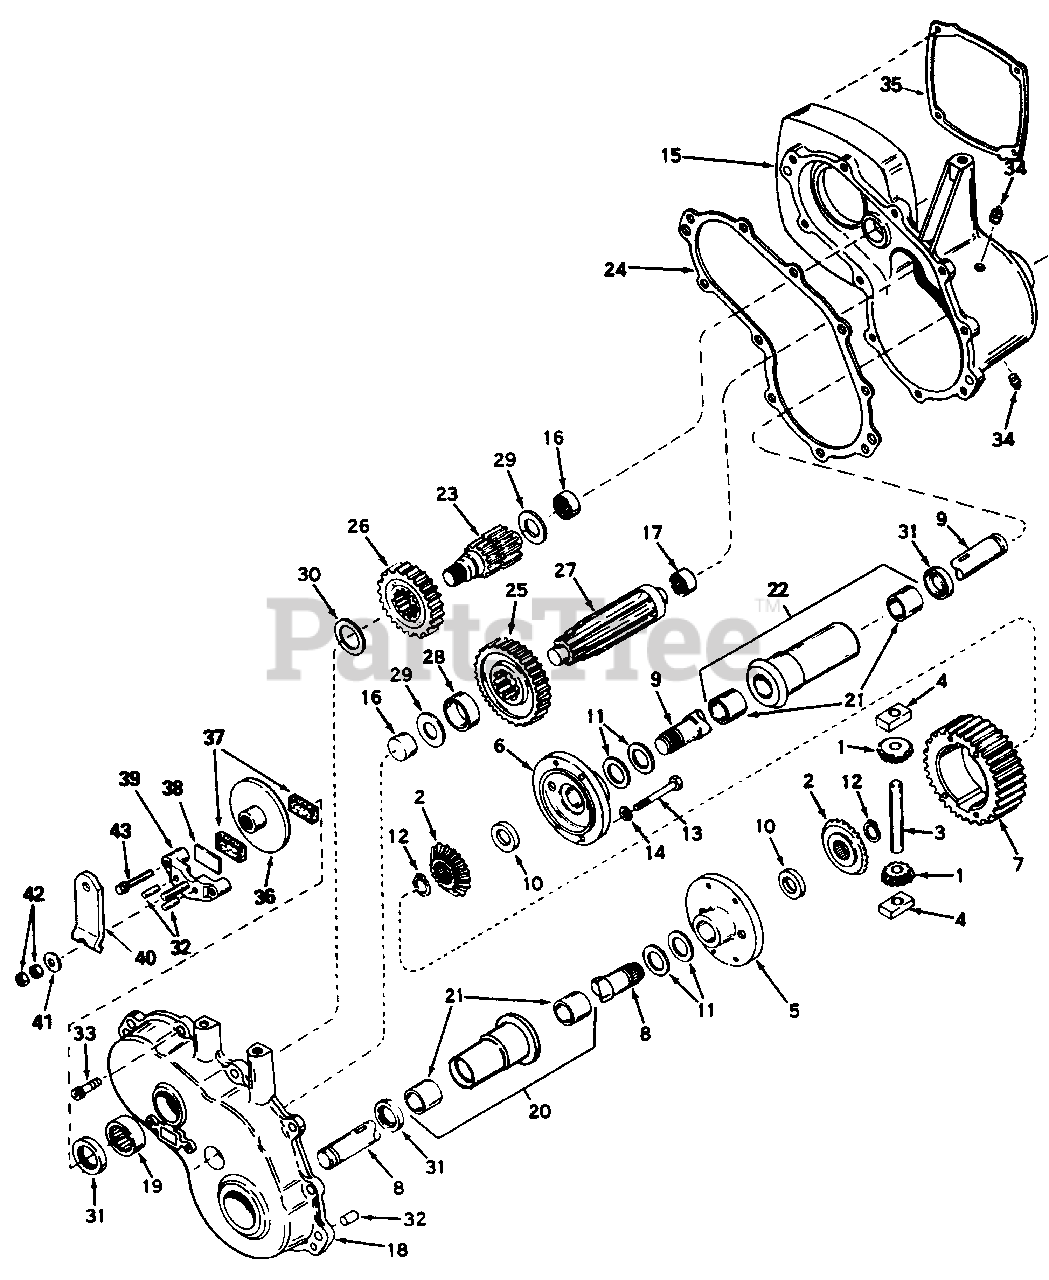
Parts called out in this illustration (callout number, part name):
1	PINION, Bevel
2	GEAR, Bevel
3	PIN, Drive
4	BLOCK, Drive
5	CARRIER, Differential
6	CARRIER, Differential
7	GEAR, Ring
8	AXLE (13-7/32" long)
9	AXLE (15-3/16" long)
11	WASHER, Thrust
12	RING, Snap
13	SCREW, Hex Hd.. 1/4-20 x 2-1/4
14	LOCKWASHER, 1/4
15	CASE ASSY. (Includes Ref. Nos. 16 & 17)
16	BEARING, Needle
17	BEARING, Needle
18	COVER ASSY. (Includes Ref. Nos. 16 & 19)
19	BEARING, Needle
20	HOUSING & BUSHING ASSY. (6-5/8" long)
22	HOUSING & BUSHING ASSY. (8-5/8" long)
23	SHAFT, Brake
24	GASKET, Case-to-Cover
25	GEAR, Output
26	Gear, Idler
27	SHAFT, Output
31	SEAL, Oil
32	PIN, Dowel
33	SCREW, Hex Wash. Hd., Thd. Form., 1/4-20 x
34	PLUG, Pipe
36	DISK, Brake
37	PAD, Brake
38	PLATE, Brake Pad
39	HOLDER, Brake Pad
40	LEVER, Brake
41	WASHER, Flat
42	LOCKNUT, 5/16-24
43	SCREW, Hex Hd., Thd. Form., 1/4-20 x 1
